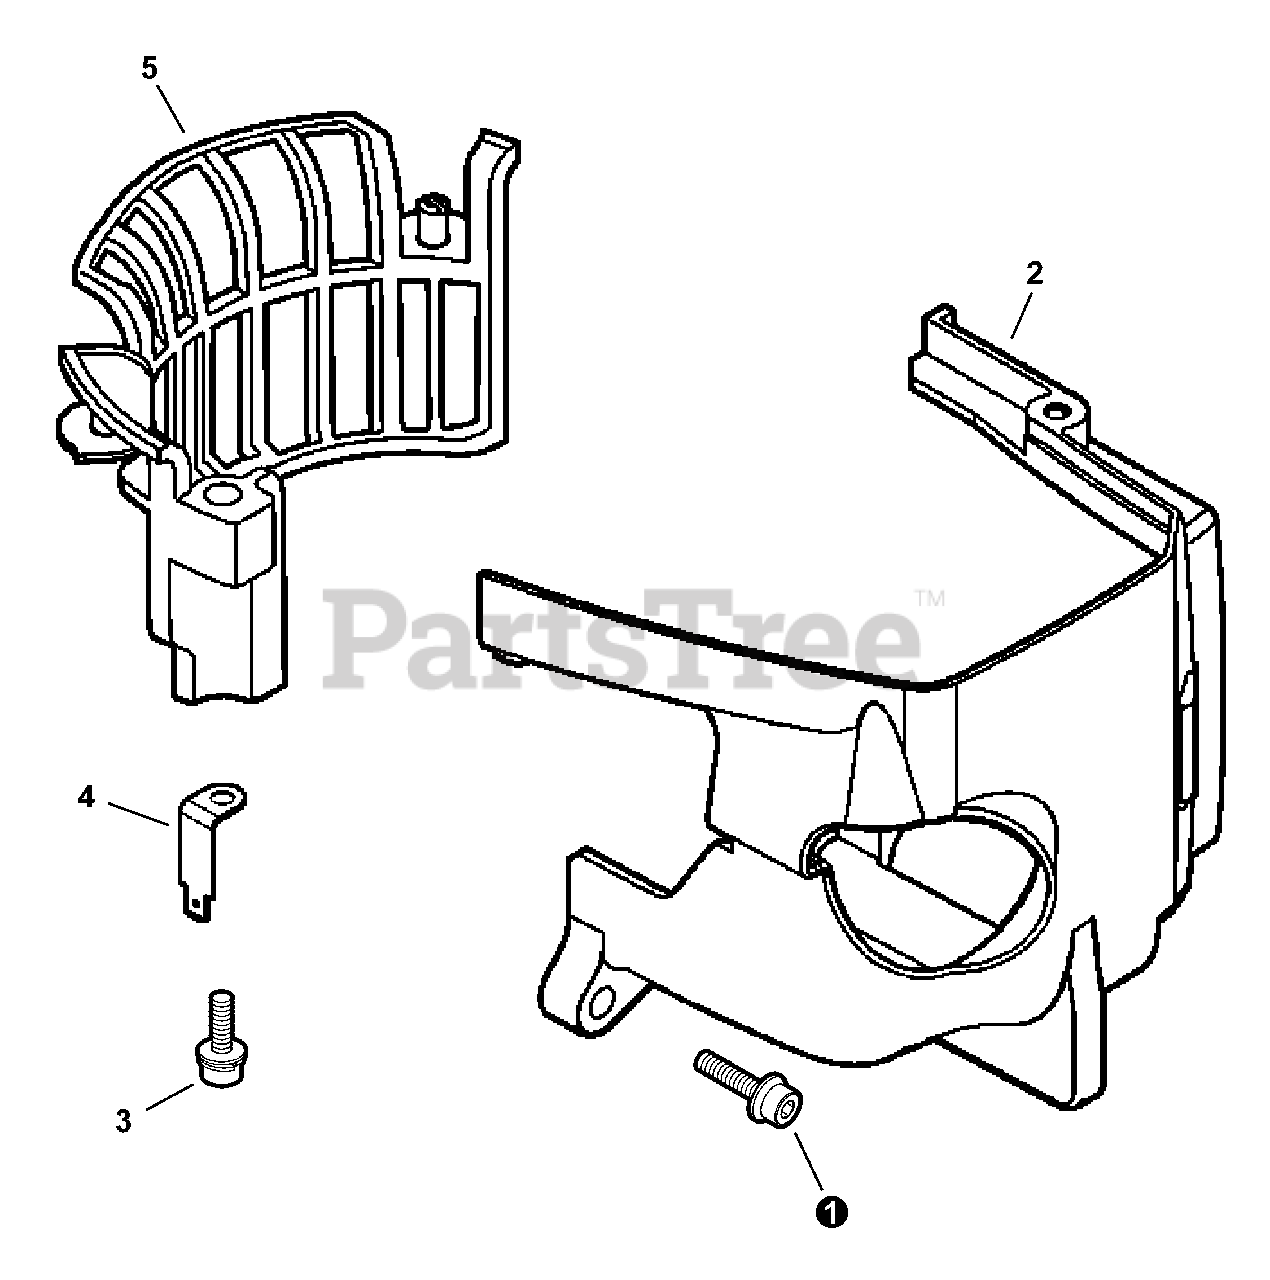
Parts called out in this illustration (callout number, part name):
1	BOLT 5×16
2	COVER, ENGINE
3	BOLT 5×16
4	CONNECTOR
5	SHIELD, DEBRIS
